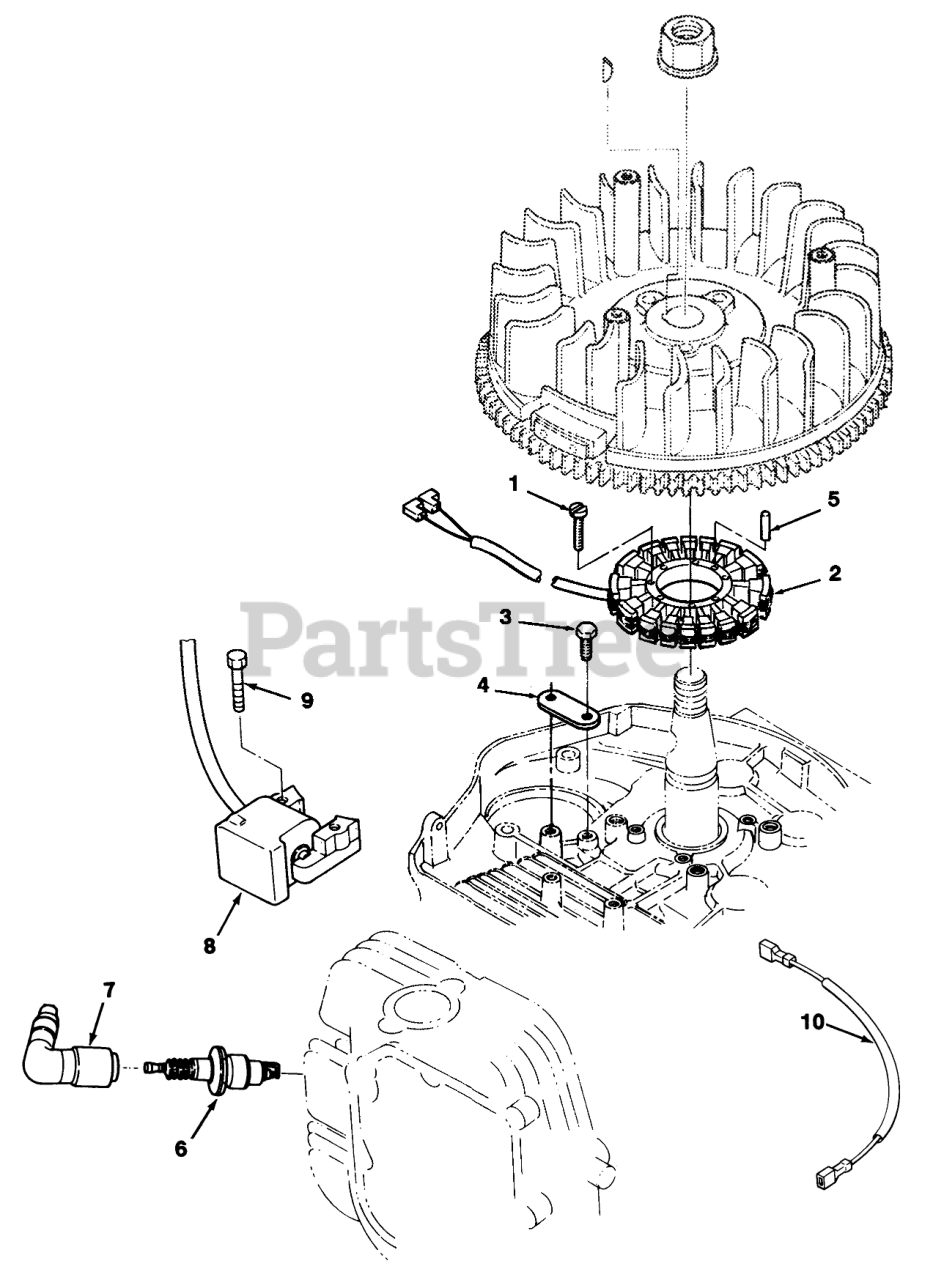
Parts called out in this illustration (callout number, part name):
1	SCREW
2	STATOR
3	HHSTB-M6 X 14MM
4	CLAMP-CORD
5	PIN-ALIGNMENT
6	SPARK PLUG
8	COIL-IGNITION
9	HHSTB-M6 X 27MM
10	HARNESS
